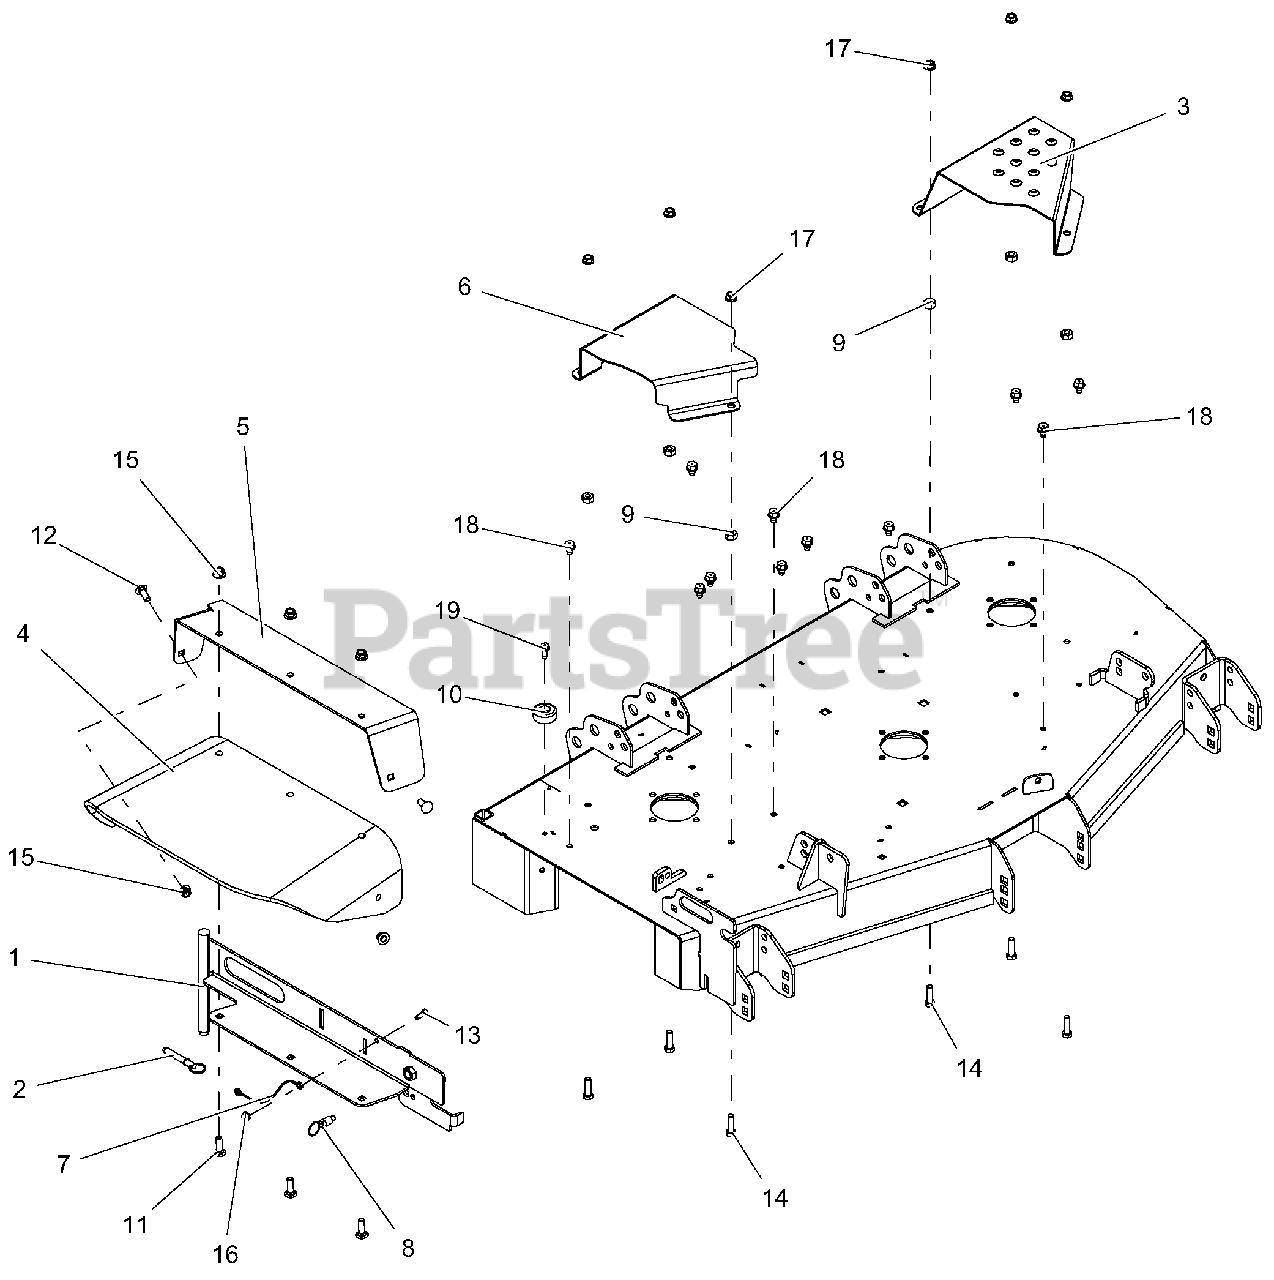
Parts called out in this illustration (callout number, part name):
1	WLDMT, 44"-48" DISCH CHUTE MTG-RED
2	PIN, SPRING BALL .375 OD X 1.50
3	GUARD, 44-52" LH DECK BELT-BLACK
4	CHUTE, RUBBER DISCHARGE
5	SUPPORT, CHUTE MOUNTING BRACKET-RED
6	GUARD, 48"-52" RH DECK BELT-BLACK
7	CABLE, 6.0 LANYARD, NYLON
8	PULL PIN,.50-13THDX.310 PLNGR
9	NUT-HEAVY HEX .38-16 YWZC
10	BUMPER, RECESSED 1.50 X .63 W/.31 HOLE
11	BLT-RDHDSQNK .38-16X1.25 G5 YWZC
12	BLT-RDHDSQNK .38-16X1.00 G5 YWZC
13	BLT-HEX .25-20X.75 GR5 YWZC
14	BLT-HEX .38-16X1.25 GR5 YWZC
15	NUT-LK-NYL-FLG .38-16 YWZC
16	NUT, LK-TOP-FLG .25-20 YWZC
17	@NUT-SPNLK-FLG .375-16 YWZC
18	SCR-TAP .38-16X.50 HWH TR YWZ
19	SCR-TAP .31-18X.75 HWH TR YWZ
